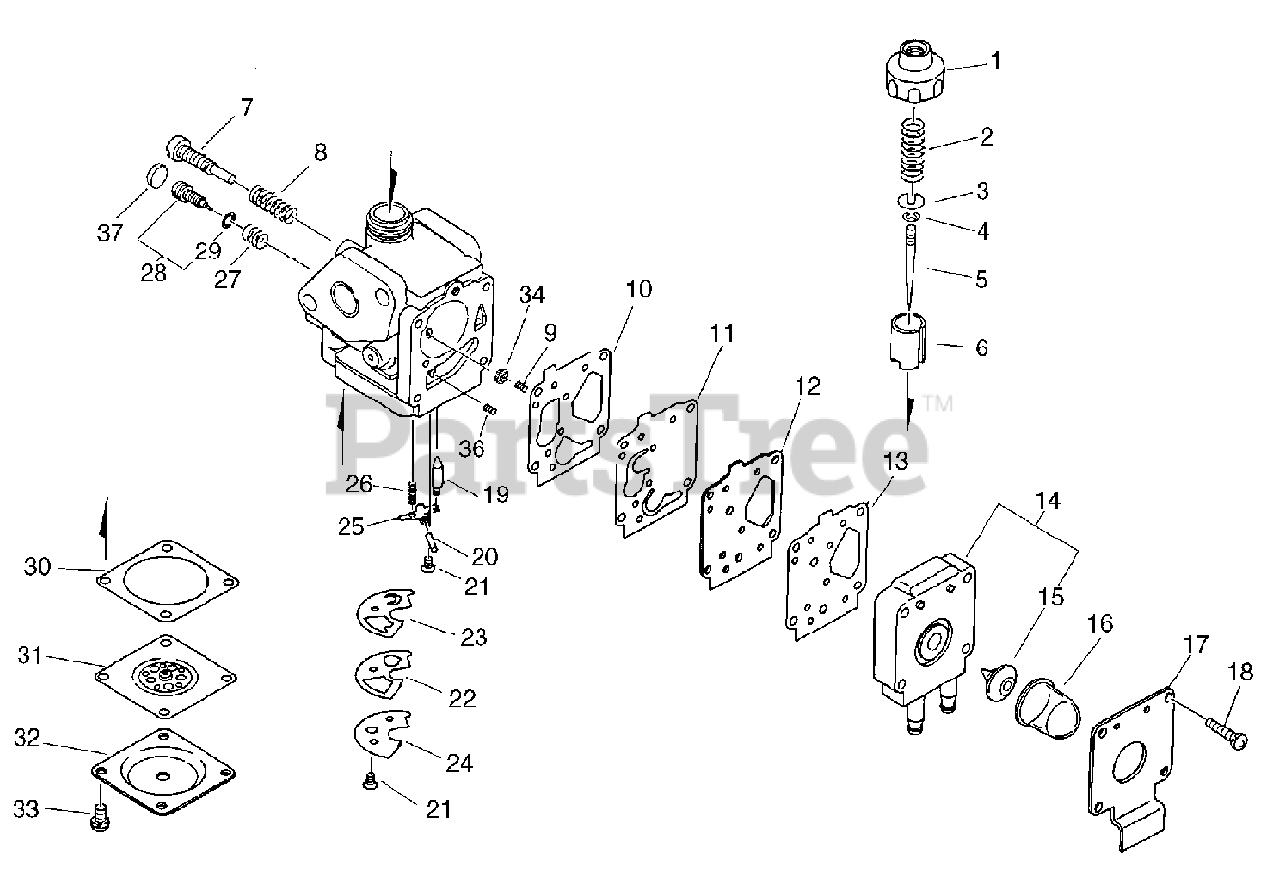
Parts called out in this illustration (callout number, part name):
1	COVER - TOP
2	SPRING, THROTTLE
3	SEAT, SPRING
4	RING, RETAINING
5	NEEDLE, JET
6	VALVE, THROTTLE
7	SCREW, IDLE ADJUST
9	SPRING, CHECK VALVE
9	SPRING, ADJUST
10	GASKET, PUMP
11	DIAPHRAGM, PUMP
12	PLATE, PUMP
13	GASKET, PUMP
14	COVER, PUMP
15	VALVE, CHECK
16	BULB, PURGE
17	COVER, PUMP
18	SCREW - 3X14
19	VALVE, NEEDLE
20	PIN, METERING LEVER
21	SCREW - 3X8
22	VALVE, CHECK
25	LEVER, INLET
27	SPRING, ADJUST
28	NEEDLE - HIGH SPEED
28	SCREW, MAIN ADJUST
30	GASKET, DIAPHRAGM
31	DIAPHRAGM
32	COVER, DIAPHRAGM
33	SCREW - 3X8
34	STRAINER
37	PLATE
